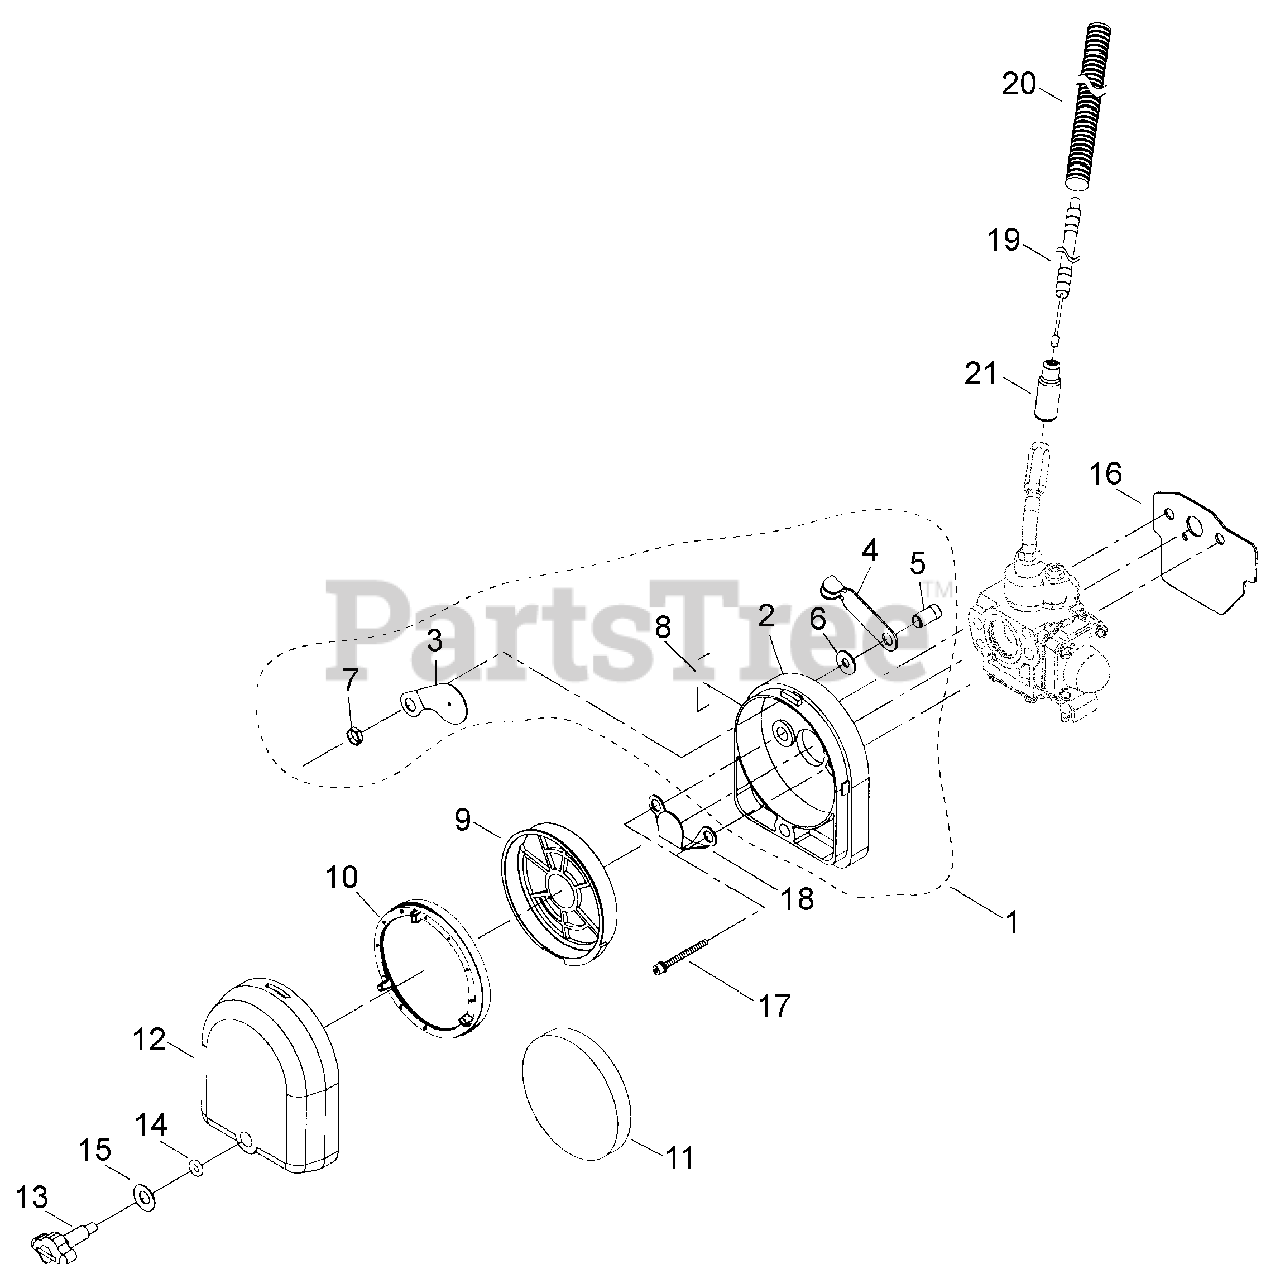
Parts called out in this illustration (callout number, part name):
1	CASE ASSY, AIR FILTER
2	CASE, AIR FILTER
3	PLATE, CHOKE
4	LEVER, CHOKE
5	SHAFT, CHOKE
6	WASHER, CONE M6
7	U-NUT M6
8	LABEL, CHOKE
9	SCREEN, REAR AIR FILTER
10	FILTER, HEAVY-DUTY AIR
11	FILTER, AIR
12	COVER, AIR FILTER
13	THUMBSCREW
14	O-RING
15	WASHER, CONE M6
16	GASKET, CARBURETOR
17	BOLT M5×50
18	PLATE
19	CABLE, THROTTLE
20	TUBE, PLASTIC PROTECTIVE
21	CAP, CARBURETOR
